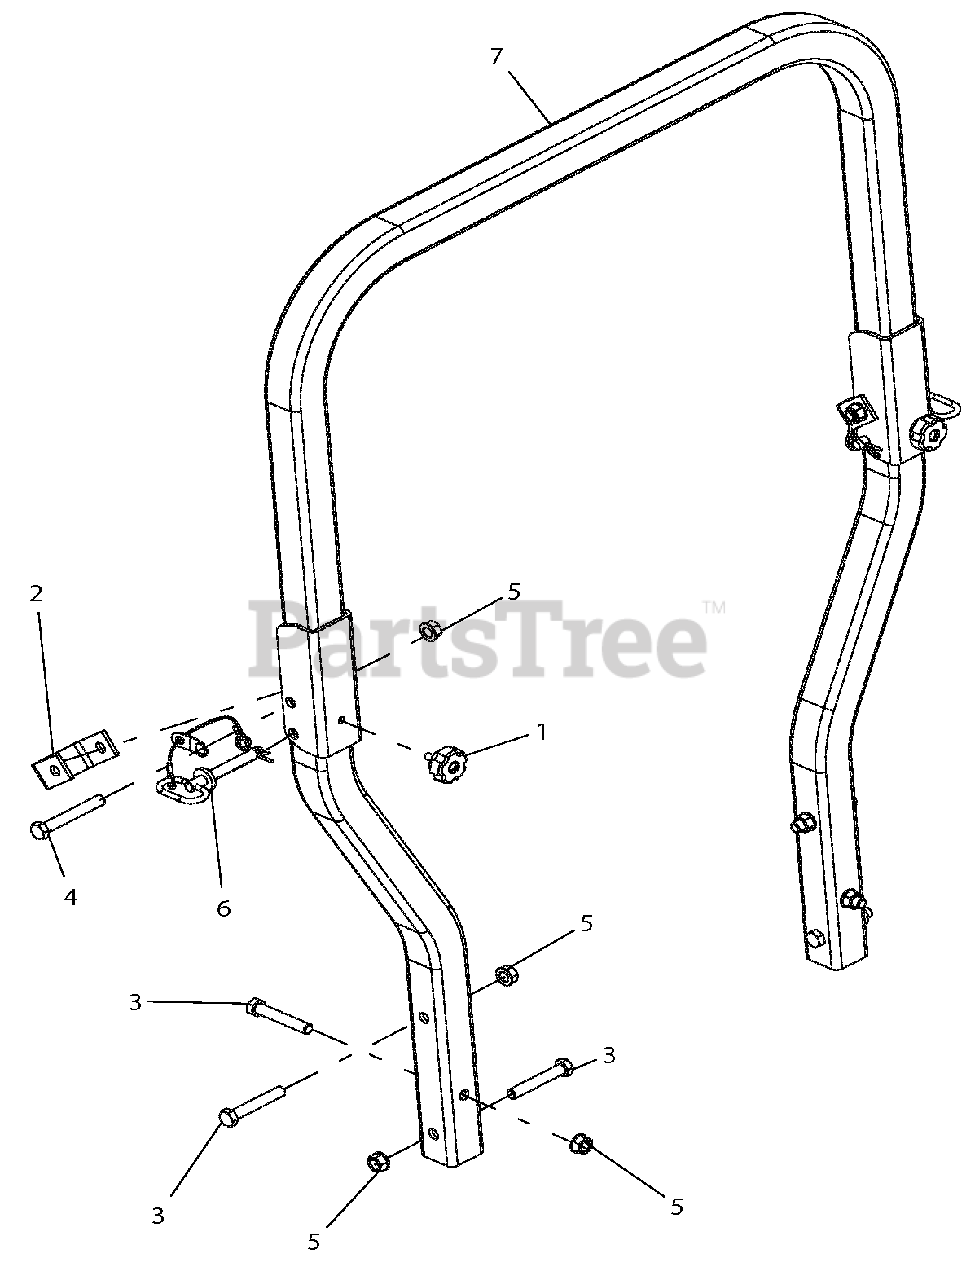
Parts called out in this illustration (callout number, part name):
1	KNOB, ROUND 5/16-18 X .750
2	BRKT, ROPS STOP
3	BLT-HEX .50-13X3.00 GR5 YWZC
4	BLT-HEX .50-13X3.50 GR5 YWZC
5	NUT, LK-TOP-FLG .50-13 YWZC
6	ASSY, ROPS PIN/LANYARD
7	ROPS INCLUDES HOOP RH AND LH SUPPORT
